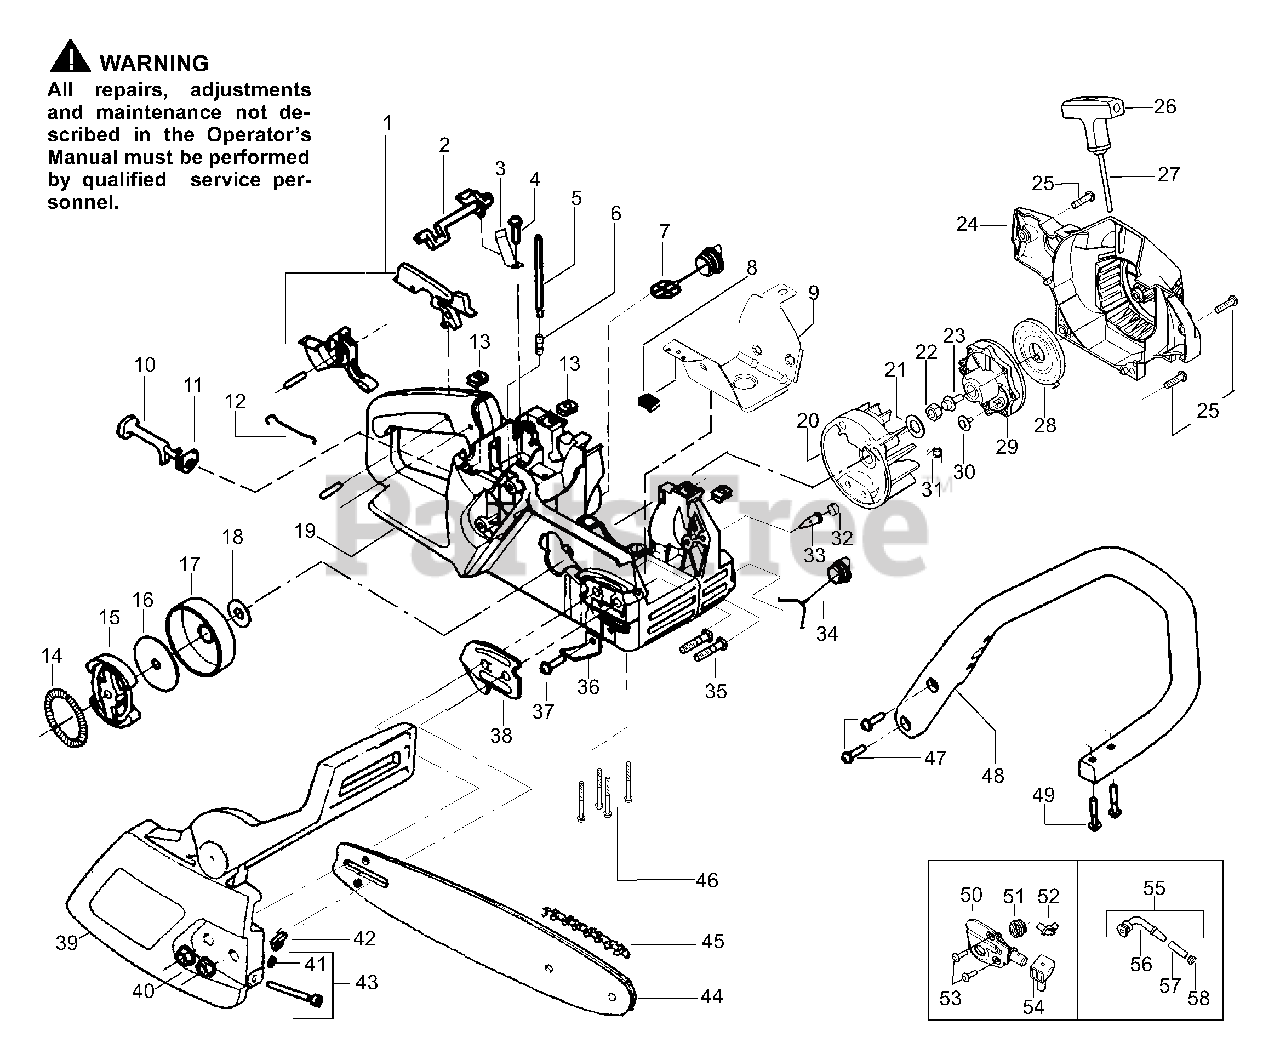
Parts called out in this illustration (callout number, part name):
1	Trigger & Lockout Kit
2	Switch Lever
3	Switch Spring
5	Fuel Line Kit (Large)
6	Fitting - Fuel line
7	Fuel Cap Ass'y.
8	Clip - "U"
9	Shield - Heat
10	Lever-Choke
11	Grommet-Choke lever
12	Wire-Throttle
13	Nut-Speed
14	Spring - Clutch
15	Assy.-Clutch
16	Washer-Clutch
17	Drum Assy. W/brg.
18	Washer - Thrust
19	Kit - Chassis Assy.
20	Flywheel Ass'y.
21	Washer-Flywheel
22	Nut-Flywheel
24	Fan Housing
26	Starter Handle
27	Rope Kit
28	Starter Spring
29	Starter Pulley
31	Spring - Starter Dog
32	Plug - Bronze Vent
33	Check Valve
34	Oil Cap Ass'y.
35	Bolt - Bar
36	Chain Catcher
38	Plate-Bar Mounting
39	Assy.-Chain Brake
40	Nut-Bar Mounting
41	Retainer-Bar Adjust
42	Pin-Bar Adjust
43	Kit-Bar Adjust
45	Chain-16"
48	Front Handle
50	Kit-Oil Pump
51	Gear-Worm Spring
52	Elbow-Oil Pickup
54	Seal Block
55	Oil-Pickup Ass'y.
56	Oiler Pickup
57	Oil Filter
58	Plug-Oil Filter
